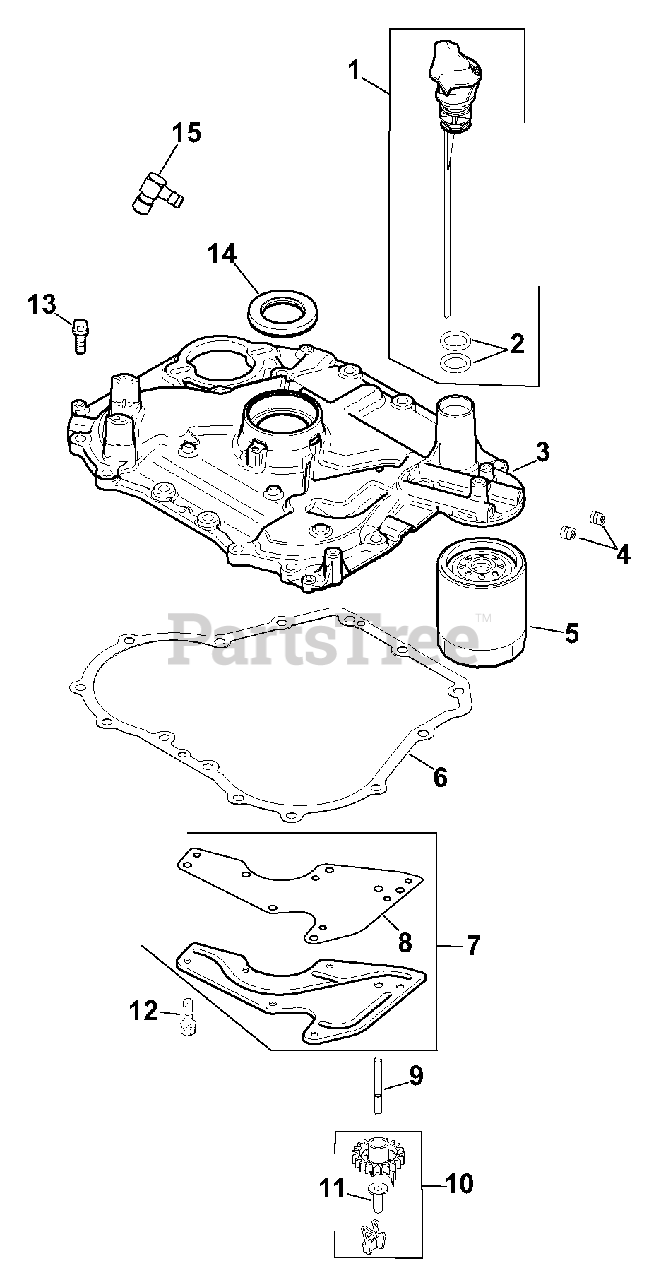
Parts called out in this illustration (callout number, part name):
1	Kit, Dipstick Blade
2	O-ring
3	Kit,plate, Closure Bearing
4	Plug, CTSK Pipe 1/8"
5	Filter, Oil
6	Gasket, Closure Plate
7	Kit, Oil Passage Cover
8	Gasket, Oil Passage
9	Shaft, Governor Cross
10	Kit, Governor Gear Assy
11	Pin, Governor Regulating
12	Screw, Flg Thd Frm M5x0.8x13
13	Screw, Flg M8x1.25x30
14	Seal, Oil
15	Connector, 90° Hose
